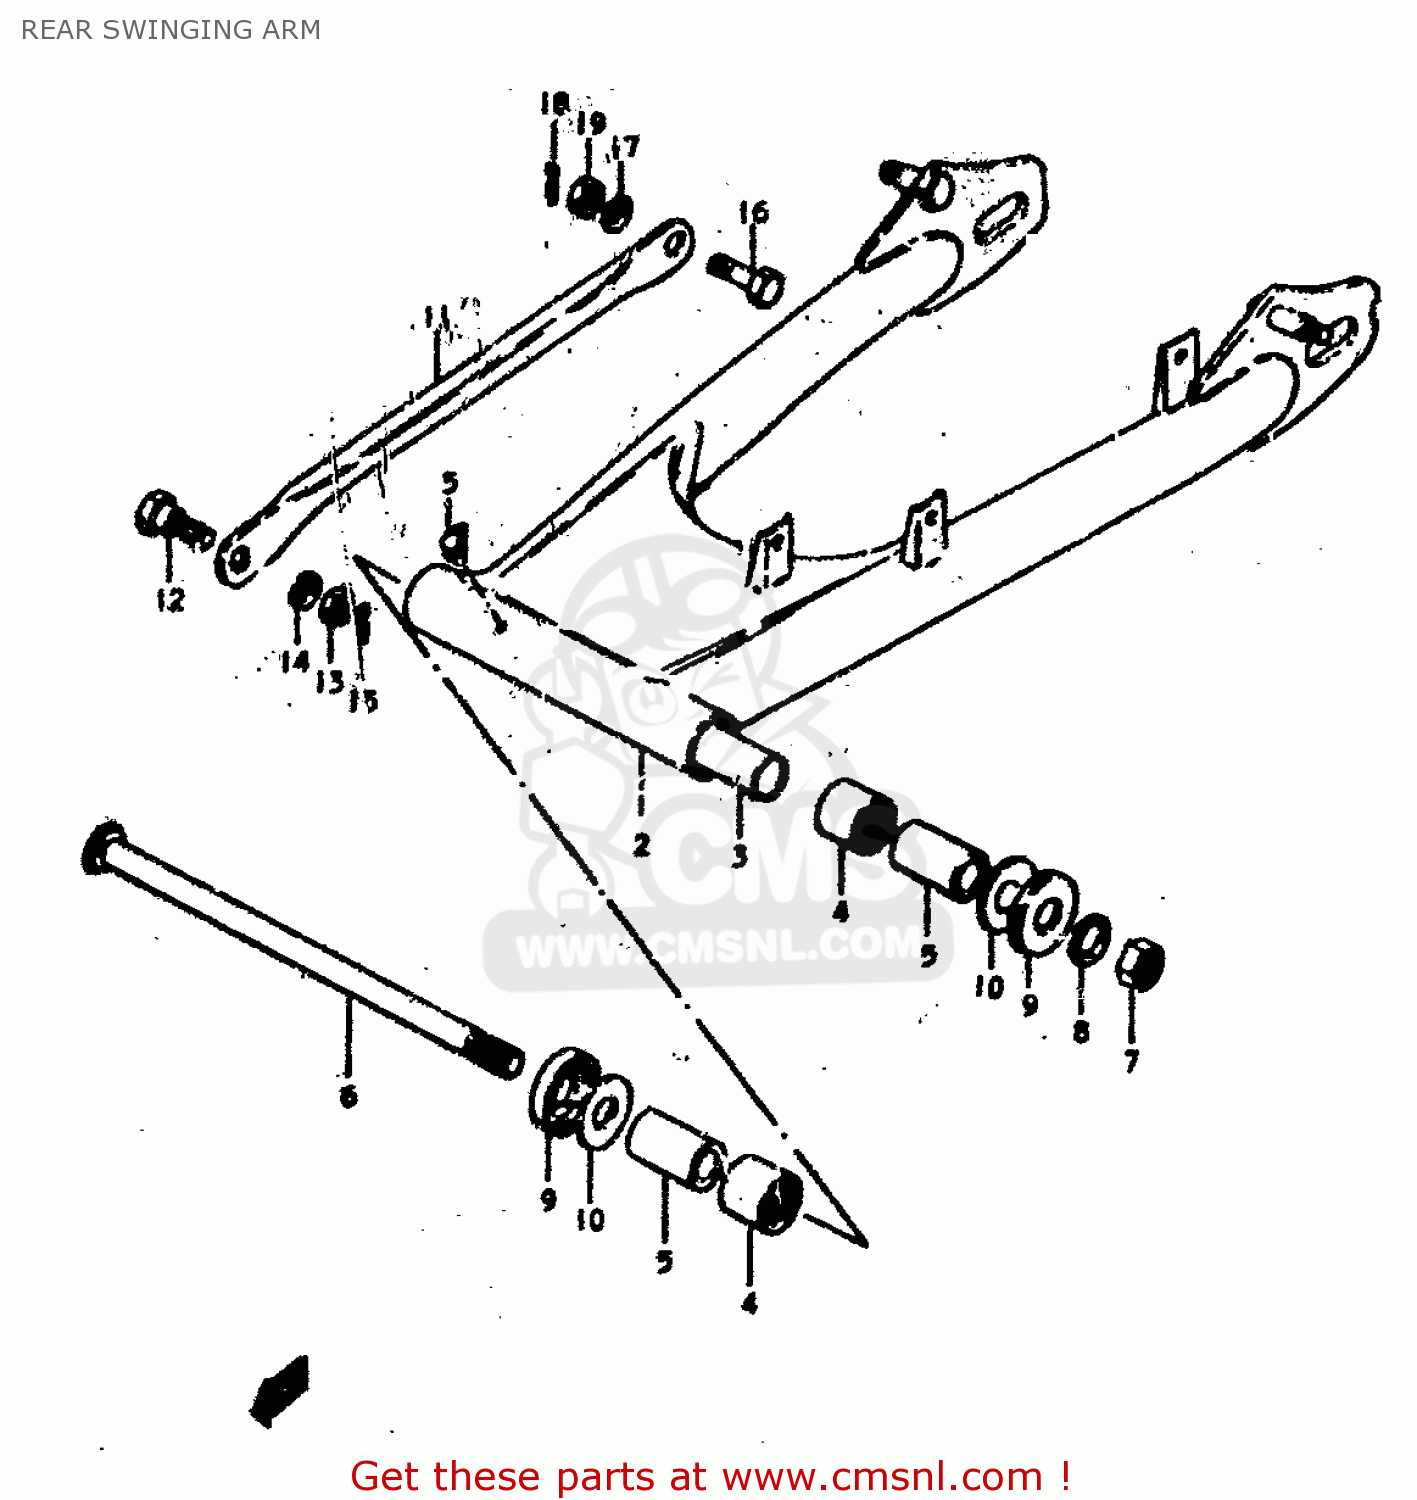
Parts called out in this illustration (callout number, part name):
1	SWING ARM ASSEMBLY,REAR
3	SPACER,SWING ARM,CENTER
4	BEARING(22X29X30)
5	SPACER,RR SWGARM PIVOT
6	SHAFT,REAR SWING ARM
7	NUT 14MM
8	WASHER
9	COVER,REAR SWING ARM DUST
10	WASHER(14.2X34X1)
11	TORQUE LINK,REAR
12	BOLT(10X24.5)
13	NUT
14	LOCK WASHER
15	CLIP
16	BOLT(10X31)
17	LOCK WASHER
18	CLIP
19	NUT
